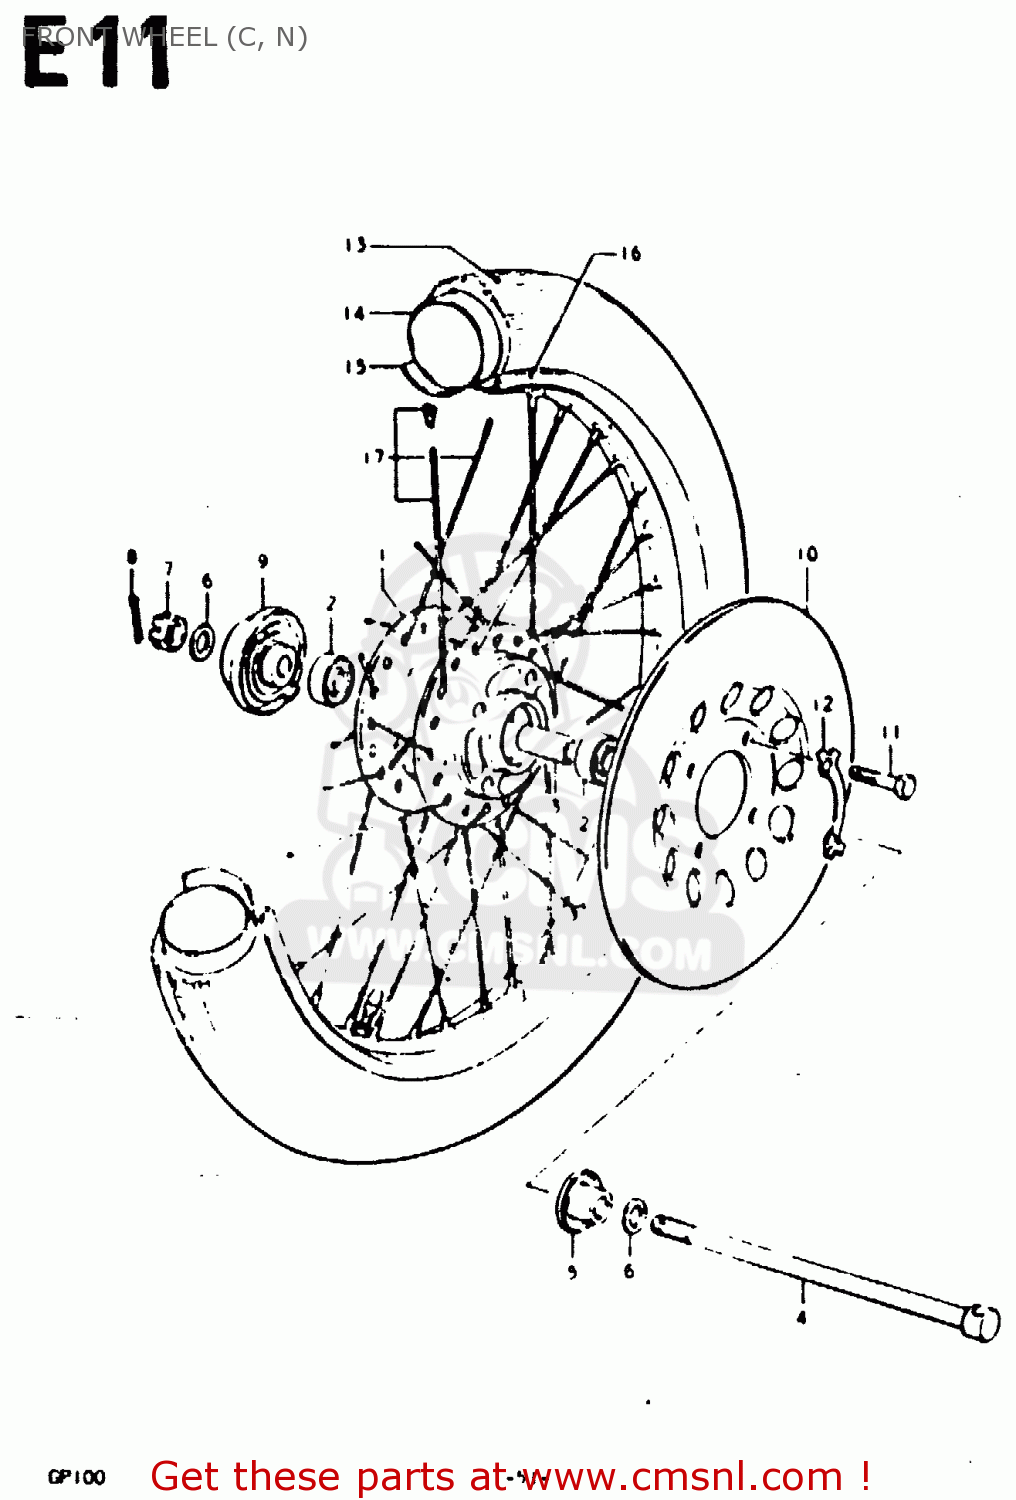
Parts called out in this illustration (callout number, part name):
1	HUB,FR
2	BEARING
3	SPACER (10.2X16X51)
4	AXLE,FRONT
5	SPACER,FR AXLE,L
6	WASHER
7	NUT
8	COTTER PIN
9	BOX ASSY, SPEEDOMETER GEAR
10	DISK, BRAKE
11	BOLT(8X30)
12	WASHER
13	TIRE,FRONT
14	TUBE,INNER
15	PROTECTOR,WHEEL,INNER
16	RIM,WHEEL
17	SPOKE SET,FRONT
